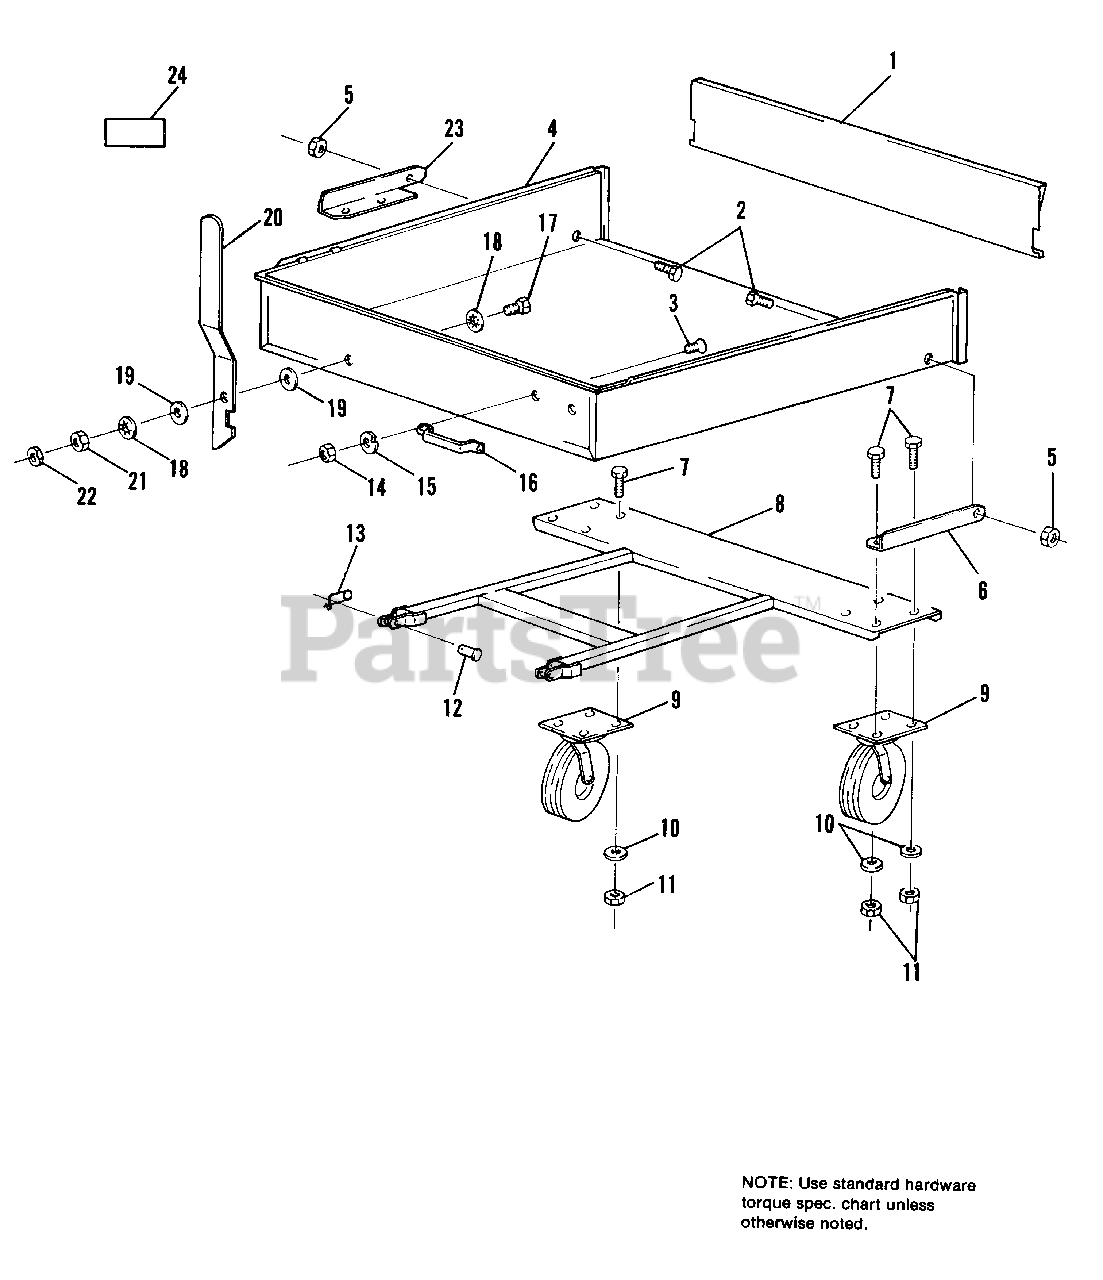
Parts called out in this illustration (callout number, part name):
2	CAPSCREW, 1/2-13 x 1
3	CAPSCREW, Hex, 1/4-20 x 1/2
5	LOCKNUT, Hex, Flange, 1/2-13
6	BRACKET, Pivot, L.H.
7	CAPSCREW, Hex
9	WHEEL, Swivel
10	WASHER, 3/8
11	NUT, Hex, Lock, 3/8-16
12	PIN, Clevis, 1/2 x 1-1/2
13	PIN, Safety
14	NUT, Hex, 1/4-20
15	LOCKWASHER, 1/4
16	HANDLE, Lift
17	CAPSCREW, 5/16-18 x 1-1/4
18	WASHER, 5/16
19	WASHER, Spring, Special, 5/16
20	HANDLE, Latch
21	NUT, Hex, Full, 5/16-18
22	NUT, Hex, Jam, 5/16-18
23	BRACKET, Pivot, R.H.
24	DECAL, Max. Capacity
